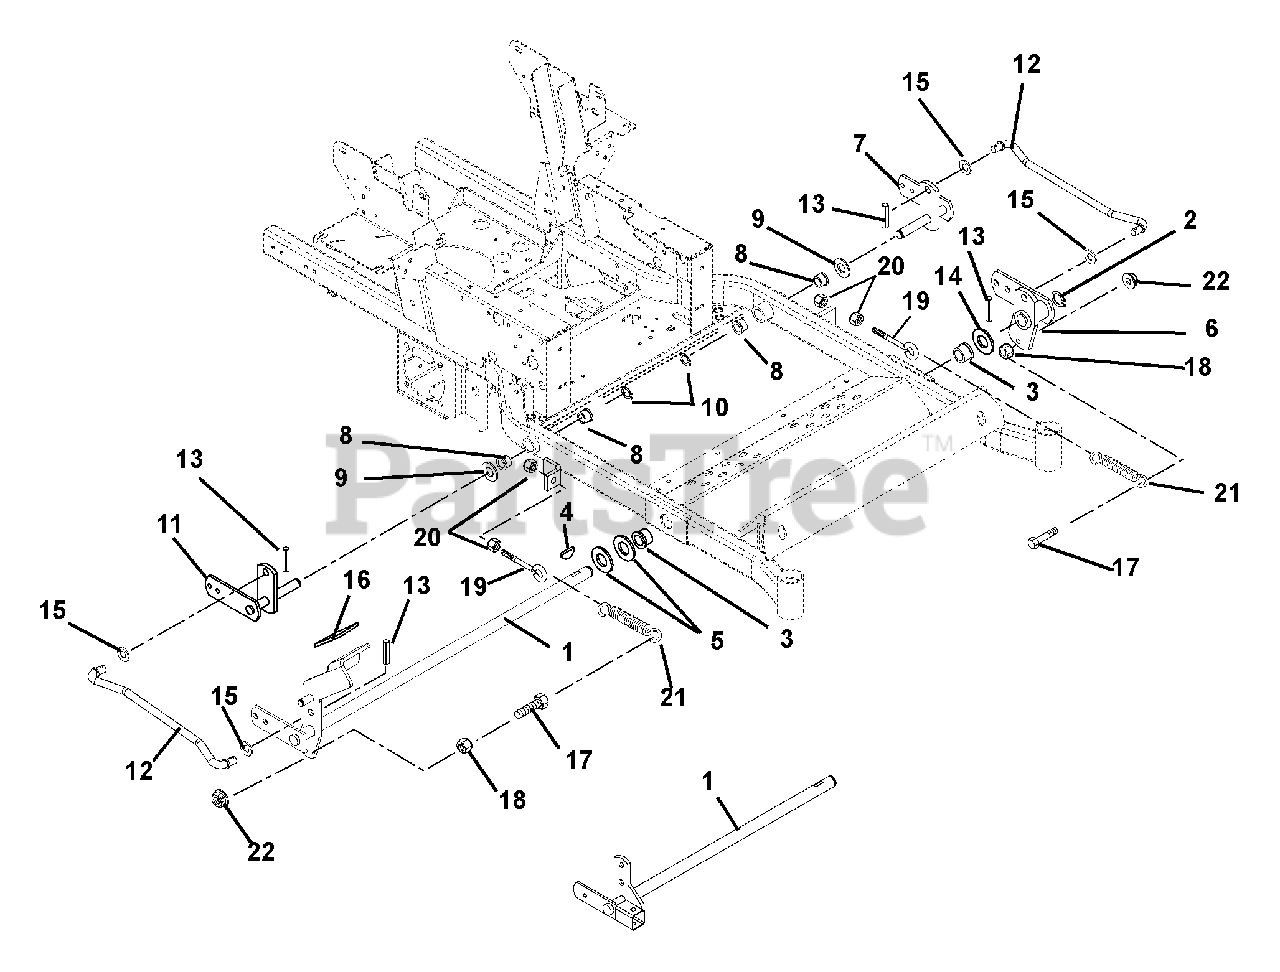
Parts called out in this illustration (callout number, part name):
1	Weldment, Lift Arm (992042, 043, 044, 051, 054, 055, 077, 078, 079, 080, 081, 082, 310, 311)
1	Weldment, Lift Arm (992064, 083, 092, 093, 094, 095, 096, 097)
2	Ring, Retaining External 1.00 x .078
3	Bushing, Flange Nylon 1.020 x 1.385 x .75 x 1.75
4	Key, Woodruff .25 x 1.00
5	Washer, Flat Steel 1.063 x 2.00 x .134
6	Lift Arm - Front
7	Lift Arm Shaft - Left Hand
8	Bushing, Flange Nylon .762 x 1.0 x .580 x 1.48
9	Washer, Hardened Steel .758 x 1.23 x .031
10	Ring, Retaining External .689 x .077
11	Lift Arm Shaft - Right Hand
12	Rod, Lift Assist
13	Pin, Roll .25 x 1.25 Stainless Steel
14	Washer, Hardened Thrust 1.00 x 1.55 x .03
15	Washer-Flat-Steel .630 x 1.250 x .062
16	Grip, Pedal (992064, 083, 092, 093, 094, 095, 096, 097)
17	Bolt-Hex .38-16 x 1.50 Grade 5 (992064, 083, 092, 093, 094, 095, 096, 097)
18	Nut, Flange .375-16 (992064, 083, 092, 093, 094, 095, 096, 097)
19	Eye-Bolt, .375-16 x 2.50 (992064, 083, 092, 093, 094, 095, 096, 097)
20	Nut, Hex Jam .375-16 (992064, 083, 092, 093, 094, 095, 096, 097)
21	Spring, Tension .162 x 1.25 x .25 (992064, 083, 092, 093, 094, 095, 096, 097)
22	Nut, Top Lock Flange .38-16
